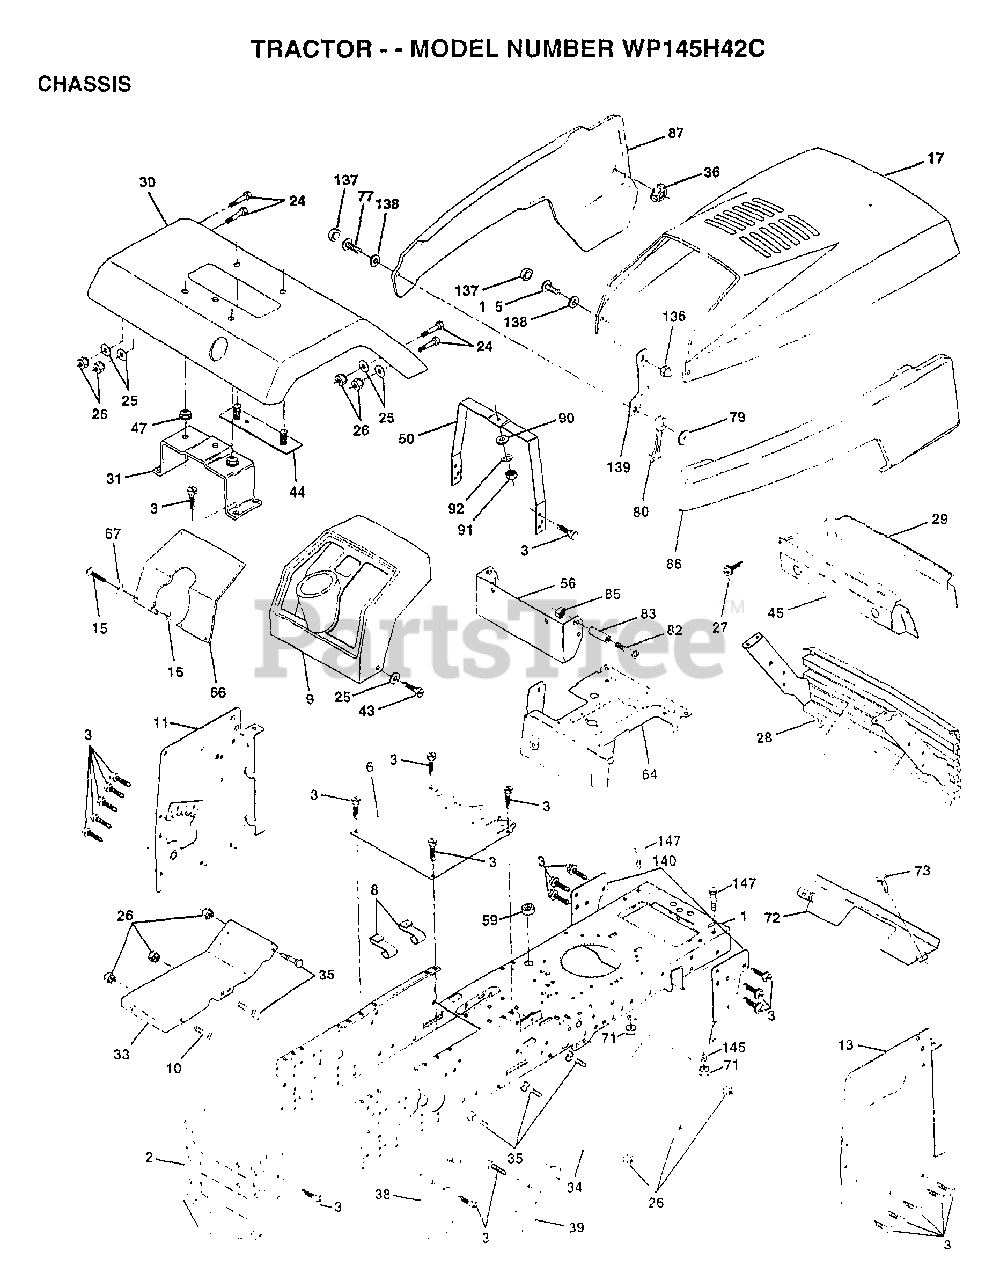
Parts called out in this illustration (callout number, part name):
1	CHASSIS ASM
3	SCREW
6	SADDLE
8	"CLIP,INSULATOR"
9	DASHBOARD BLACK
11	PANEL.DASH.LH.
13	PANEL.DASH.RH.
15	SCREW
24	BOLT
25	WASHER
26	NUT
28	GRILLE ASM PNT
29	PANEL.DASH.RH
30	FENDER.PNT.
31	BRKT.ASM.FENDER
33	FOOTREST.LH.LT/GT
34	FOOTREST.RH.LT/GT
35	BOLT
36	PAL NUT LT
38	BRACKET ASM LH
39	BRACKET ASM RH
43	SCREW GTV
44	STRAP ASM FENDER
45	BEZEL.ASM.
47	NUT-PUSH YT
50	DASH.SUPT.YP/HUSQ
56	EXT DASH LTYT
64	DASH.LOWER.LT
66	"PLATE-DASH,SLSCR"
67	WASHER
72	STRAP.GRILLE.PNT.
73	SCREW CRT
77	SCREW
79	WELDNUT
80	HOOD LATCH T
82	SCREW
83	SPACER LT
87	"PANEL SIDE,LH"
90	WASHER PM
92	LOCKWASHER
135	SCREW.10-24X3/8.
136	ACORN NUT RB
137	SNAP CAP LT
138	WASHER LT
139	BKT.SPT.HOOD/PANL
140	BRKT SUSPENSION
145	"ROD POVOT,CHASSIS"
147	BOLT LT
